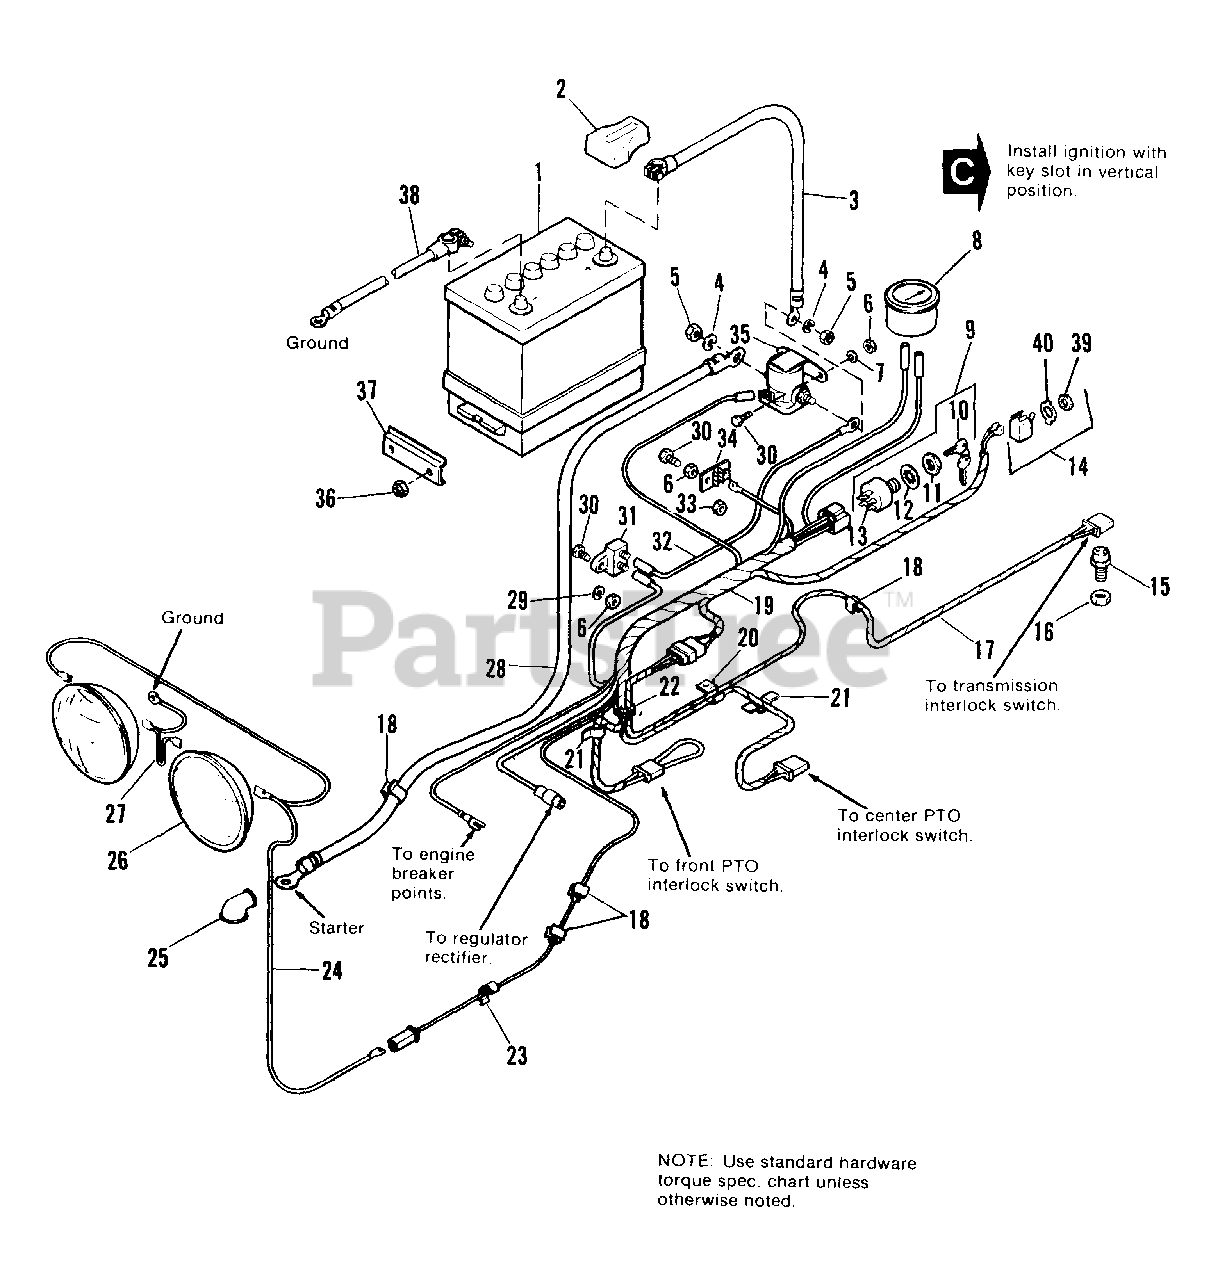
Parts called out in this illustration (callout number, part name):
1	BATTERY (Includes Decal)
2	PROTECTOR, Terminal
3	CABLE (Battery to Ground)
4	LOCKWASHER, 5/16
5	NUT, Hex, Full, 5/16-18
6	NUT, Hex, Full, 1/4-20
7	LOCKWASHER, 1/4
9	SWITCH & KEY ASSY., Ignition
10	KEY SET (2)
11	NUT, Special
12	LOCKWASHER, Internal, 5/8
14	SWITCH, Toggle
15	SWITCH, Interlock
16	NUT, Pal
17	WIRE ASSY.
18	CLIP, Tinnerman
19	HARNESS ASSY.
20	CLIP, Cable
21	CLIP, Wire
23	CLIP, Tinnerman
25	COVER, Terminal
26	LAMP, Sealed Beam, G.E., #4411-1
27	WIRE ASSY.
28	CABLE (Solenoid to Starter)
29	LOCKWASHER, 1/4
30	CAPSCREW, Hex Hd., 1/4-20 x 5/8
31	CIRCUIT BREAKER
33	LOCKNUT, Hex, 1/4-20
34	BOARD, Terminal
35	SOLENOID, Starter
36	NUT, Elastic, 5/16-18
38	CABLE(Battery to Ground)
39	NUT, Switch
